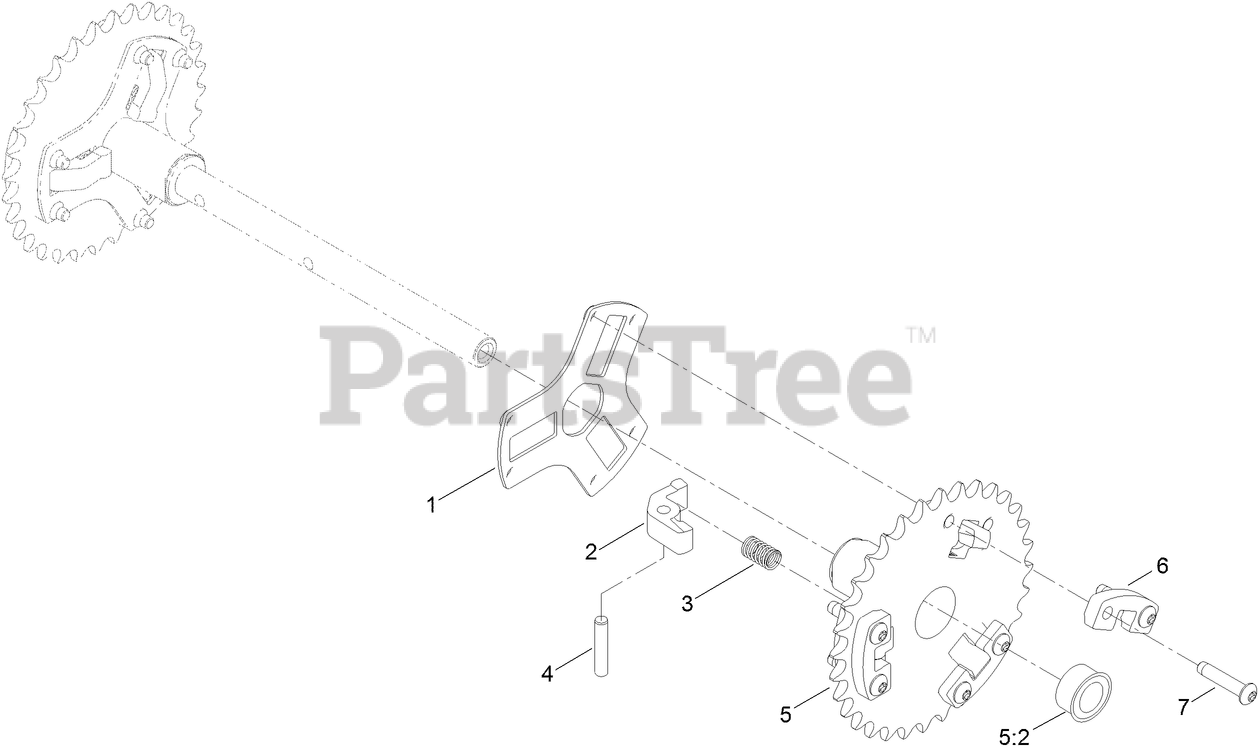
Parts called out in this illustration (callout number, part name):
1	RETAINER-PIN, PAWL
2	PAWL-CLUTCH
3	SPRING-COMPRESSION
4	PIN-DOWEL
5	32T SPROCKET ASM
5:2	BUSHING-FLANGE
6	SUPPORT-PAWL
7	SCREW-TTH, THREAD ROLLING
